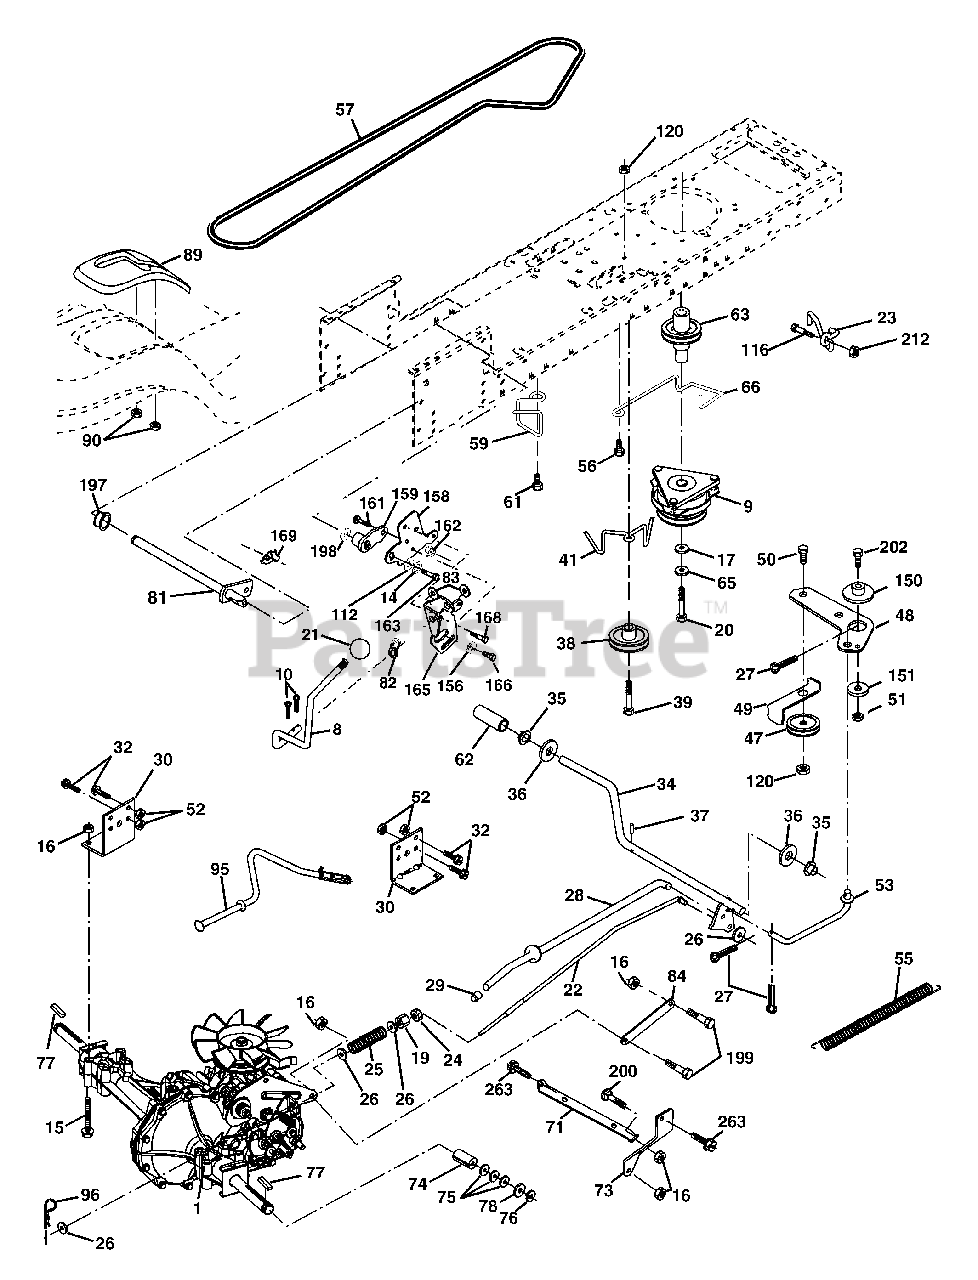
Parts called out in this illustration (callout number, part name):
8	Rod Shift Fender Adjust STLT
9	Clutch Elecric
10	Pin Cotter 1/8 x 1 CAD
14	Washer Lock Hvy Helical
15	Bolt Hex 5/16-18 unc Flghd
16	Nut Lock Hex W/Ins. 5/16-18 unc P
19	Nut Lock Hex W/Ins 3/8-16 unc
20	Bolt, Hex 7/16-20 x 4-1/4 Ga. 5
21	Knob Deluxe 1/2-13 unc BLK/BLK
22	Rod, Brake Hydro
23	Bracket Asm Mtg CL
24	Nut Hex Jam 3/8-16 unc
25	Spring, Brake Rod
26	Washer
27	Pin Cotter 1/8 x 3/4 CAD.
28	Rod, Parking Brake
29	Cap,Parking Brake
30	Bracket, Transaxle
32	Bolt Hex Hd 5/16-18 unc x 3/4
34	Shaft, Foot Pedal
35	Bearing, Nylon
36	Washer
37	Pin, Roll
38	Pulley, Composite
39	Bolt Rdhd 3/8-16 unc x 2-3/4 Gr. 5
41	Keeper, Belt Idler
47	Pulley, Idler, V-Groove Plastic
48	Bellcrank Clutch Grnd Drv STL
49	Retainer, Belt Style Spring
50	Bolt 3/8-16 x 1-1/2 Gr. 5
52	Nut Crownlock 5/16-18
53	Link, Clutch
55	Spring, Return, Clutch
56	Screw 3/8-16 x 1-1/4
57	V-Belt, Ground Drive
59	Keeper, Center Span
61	Screw 3/8-16 x .875
62	Cover, Pedal
63	Pulley, Engine
65	Washer Lock Hvy HLCL Spr 7/16
66	Keeper Belt Engine
71	Strap Torque Lh Hydro
73	Strap Torque Rh Hydro
74	Spacer, Axle
75	Washer 25/32 x 1-1/4 x 16 Ga.
77	Key, Square
78	Washer 25/32 x 1-5/8 x 16 Ga.
81	Shaft Asm Cross Tapered
82	Spring Torsion T/A
83	Washer 17/32 x 3/4 x 16 Ga.
84	Link Transaxle
89	Console, Shift
90	Nut Self Thd 1/4
95	Control Asm. Bypass Hydro
96	Retainer Spring 1" Zinc/Cad
112	Washer 9/32 x 3/4 x 10 Ga.
116	Bolt Rdhd Sqnk 3/8-16 unc x 1
120	Nut Lock Flg 3/8-16
150	Spacer Retainer
151	Washer 13/32 x 2 x 10 Ga.
156	Washer Srrted 5/16 ID x 1.125
158	Bracket Shift Mount
159	Hub Shift
161	Bolt Rdhd Sqnk 1/4-20 x 3/4 Gr. 5
162	Nut Crownlock 1/4-20 unc
163	Bolt Hex Fin 1/4-20 unc x 1 Gr. 5
165	Bracket Pivot Lever
166	Screw 5/16-18 x 5/8
168	Bolt Shoulder 5/16-18 x .561
169	Plate Fastening STLT/CRD
197	Nyliner Snap 5/8" ID
198	Washer Nyl 7/8 ID x .105 Hyd
199	Bolt Shoulder 5/16-18 unc
200	Bolt Rdhd Sqnk 5/16-18 unc x 1
202	Bolt 3/8-16 x 1-3/4 Gr. 5
212	Nut Hex Flange Lock
263	Screw Hex wsh Thdr 3/8-16 x 3/4
